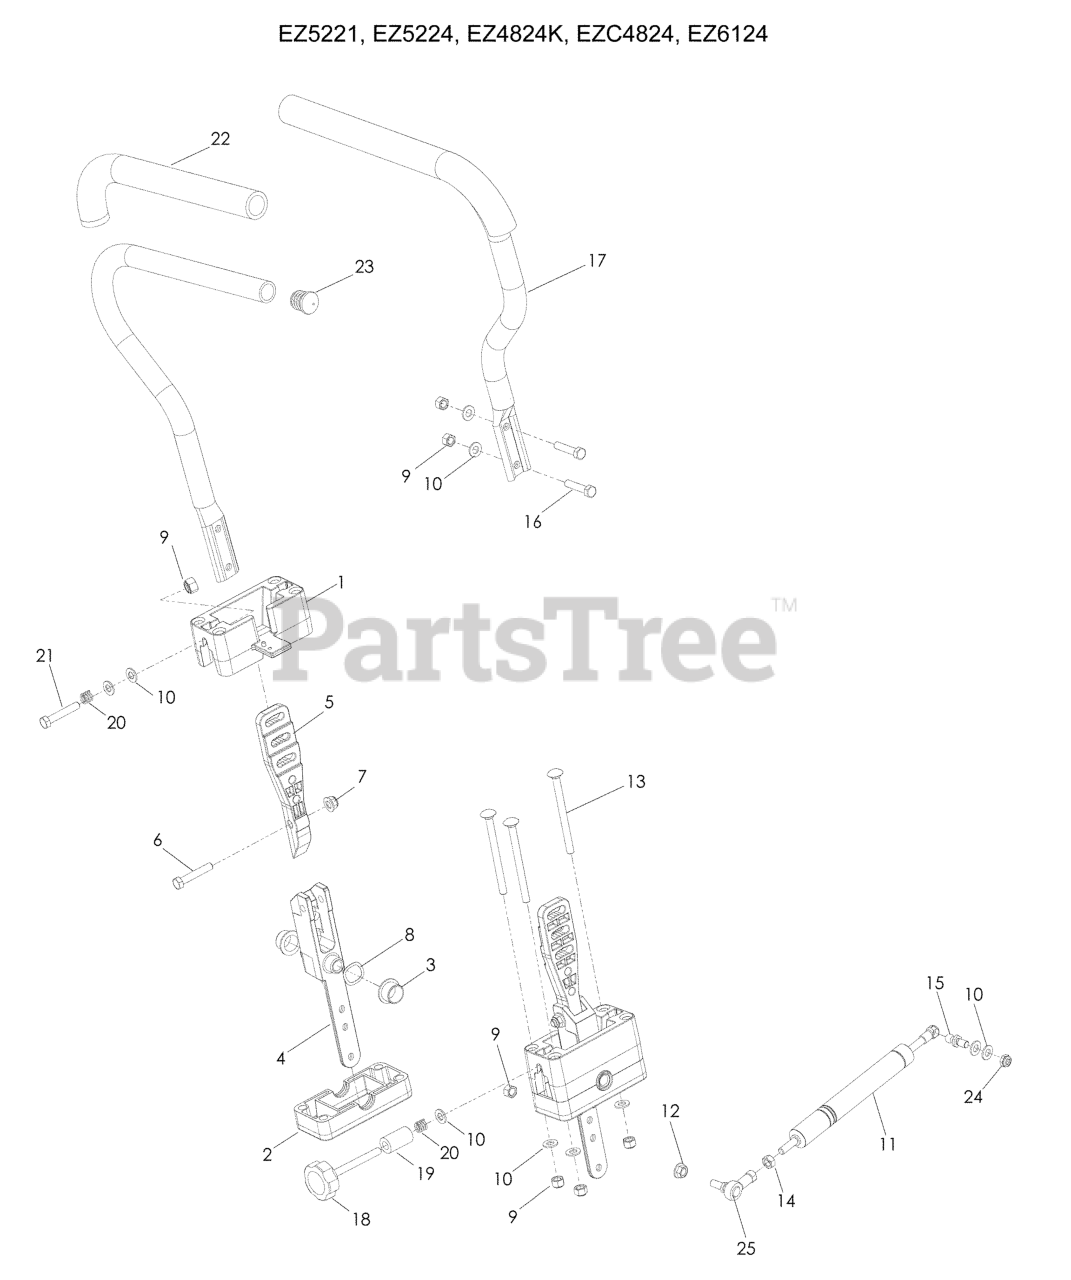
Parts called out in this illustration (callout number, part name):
1	BLOCK, UPPER
2	BLOCK, LOWER
3	BEARING, FLANGE
4	PIVOT.SECTION.DRIVE.CONTROL
5	MOUNT, DR CNTRL HANDLE
6	HCS 5/16C X 1 3/4
7	5/16-18 NYLOC FLANGE NUT
8	WASHER, .825 X 1.087, WAVE
9	NUT 5/16 NYLOC
10	FLAT WASHER 5/16 SAE
11	DAMPENER W/SPRING
12	NUT 5/16C WHIZ
13	RHSNB 5/16-18 X 4 GR 5 ZD
14	NUT M8 X 1.25 STD HEX
15	STUD.BALL.10MM
16	CAPSCREW 5/16 X 1/1/2 HEX HEAD
17	LEVER.DRIVE.W/GRIP
19	DECK LIFT SPACER
21	HCS 5/16-18 X 2 TPBLT GR 5 ZD
22	GRIP, FOAM (GROUND) 15
23	END PLUG 15/16 (BLACK)
24	5/16-18 THIN PROF NY
